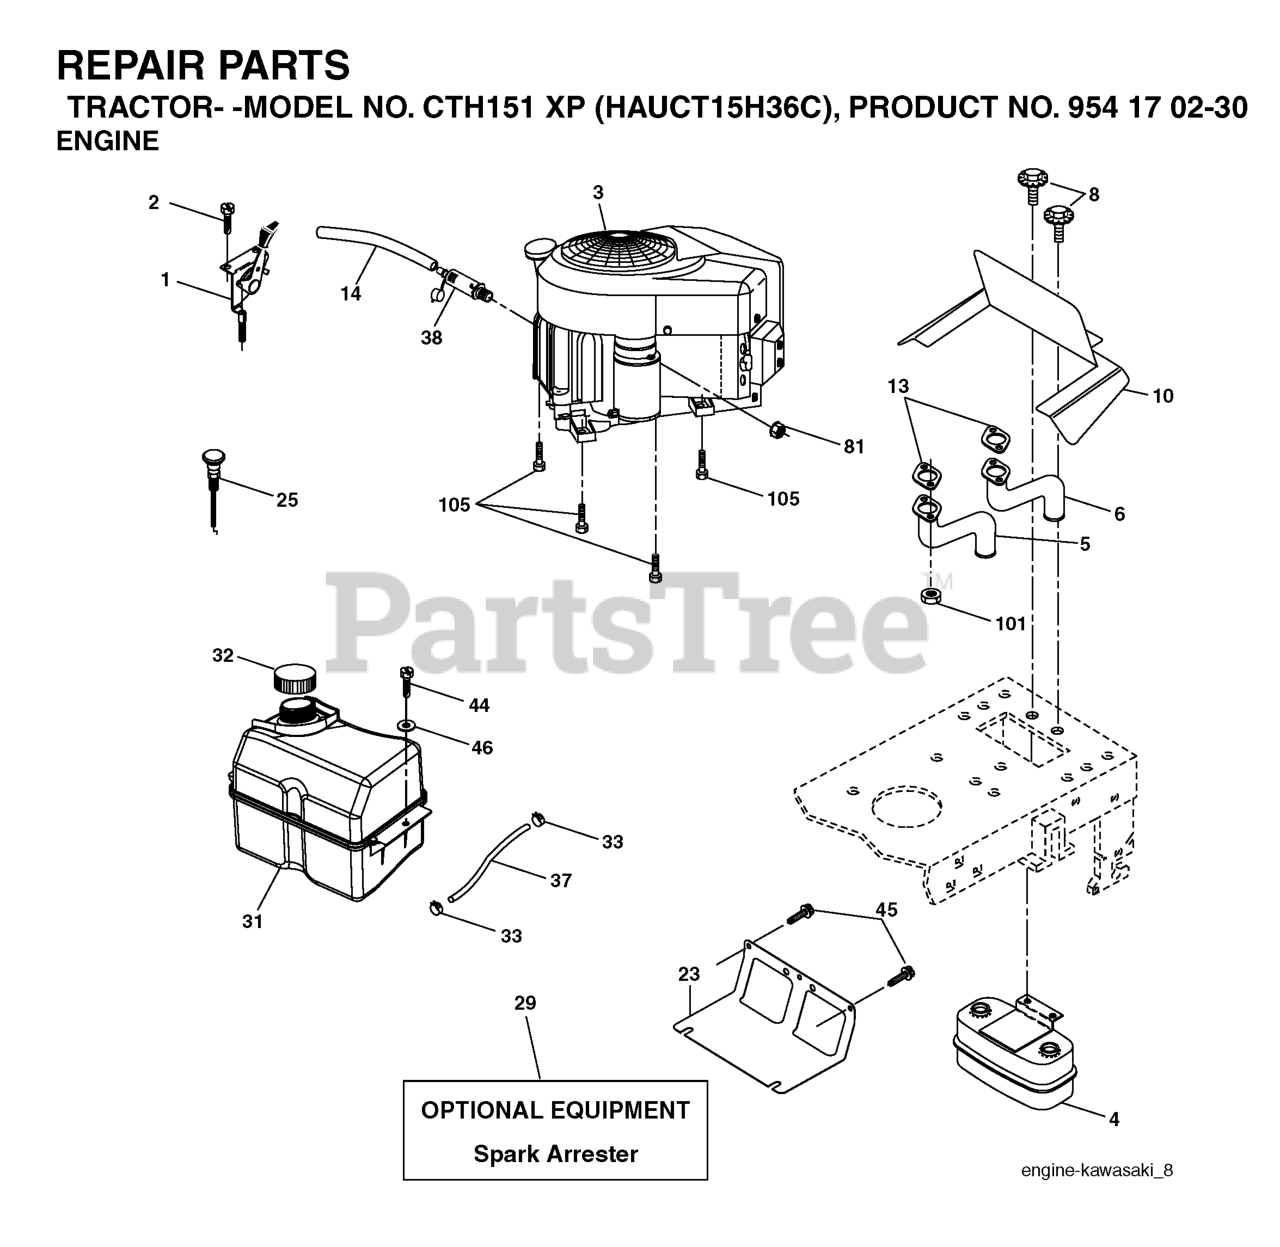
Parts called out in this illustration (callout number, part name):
1	THROTTLE CABLE
2	SCREW
4	MUFFLER.TWIN.CYL.LOW.TONE
5	EXHAUST TUBE LH KAWI
6	EXHAUST TUBE RH KAWI
8	BOLT.5/16-18UNCX3/4 W/SEMS.BLK
10	RP SHIELD HEAT MUFFLER
14	TUBE, DRAIN OIL ASM.
23	SHIELD.BROWNING.DBR.GUARD
25	CONTROL.CHOKE.ERGO.PUSH-IN.BLA
29	KIT.SPARK ARRESTOR 794945 B&S
31	TANK FUEL
32	FUEL CAP
33	HOSE CLAMP
37	LINE.FUEL.20
44	SCREW HEXWSHR 1/4-20X3/4
45	SCREW, 3/8-16X3/4
81	NUT
101	NUT.HEX.FLANGE.TOPLOCK
105	SCREW 3/8-16X1
